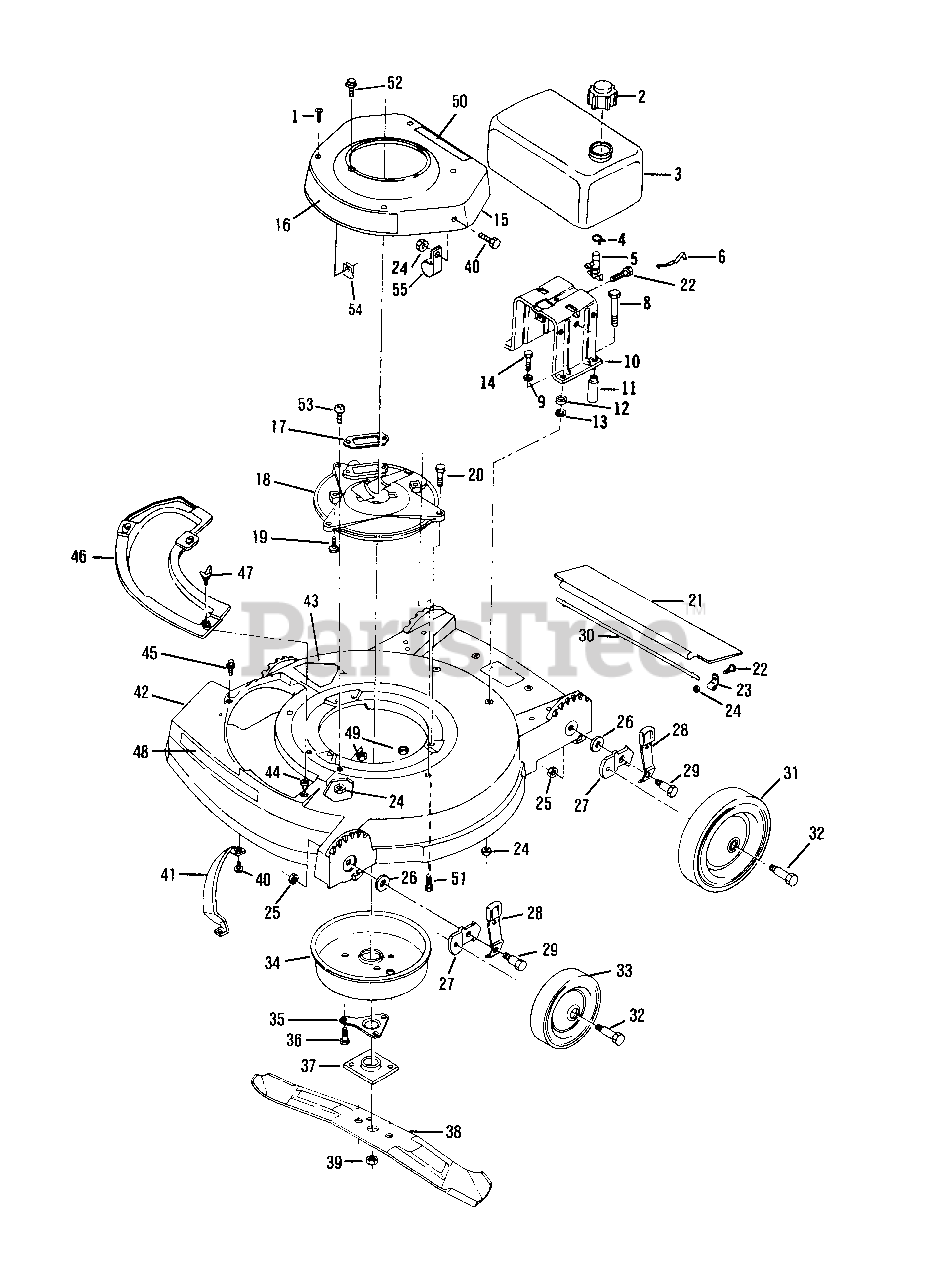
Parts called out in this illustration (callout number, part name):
1	Screw
2	Fuel Cap
3	Fuel Tank
4	Clamp
5	Shut-Off Valve and Screen
6	Spring-Fuel Tank Mounting
8	Screw
9	Washer-Tank Mounting
10	Bracket-Fuel Tank
11	Spacer-Tank Mounting
12	Grommet-Tank Mounting
13	Washer-Tank Mounting
14	Bolt-Tank Mounting
15	Shroud
16	Applique
17	Gasket-Exhaust
18	Plate-Muffler
19	Screw-Muffler Plate to Block
20	Screw-Muffler Plate to Housing
21	Shield-Trailing
22	Screw
23	Clamp
24	Nut
25	Nut
26	Washer
27	Bracket-Wheel Height Adjust
28	Knob and Spring Assembly
29	Bolt-Shoulder
30	Rod-Trailing Shield
31	Wheel-Rear-8"
32	Bolt-Wheel
33	Wheel-Front 6"
34	Muffler Cover Assembly
35	Support-Crankshaft
36	Screw-Muffler to Muffler Plate
37	Collar and Plate Assembly
38	Blade-21"
39	Nut-Blade
40	Screw
41	Toe Bar
42	Housing Assembly
43	Decal-Blade Contact Warning
44	Grommet
45	Screw-Sems-Plate Mounting
46	Cover-Chute
47	Wing Screw
48	Decal-Headliner
49	Nut
50	Decal-Fuel Mix
51	Bolt
52	Screw-Starter
53	Screw
54	Retainer
55	Clamp
